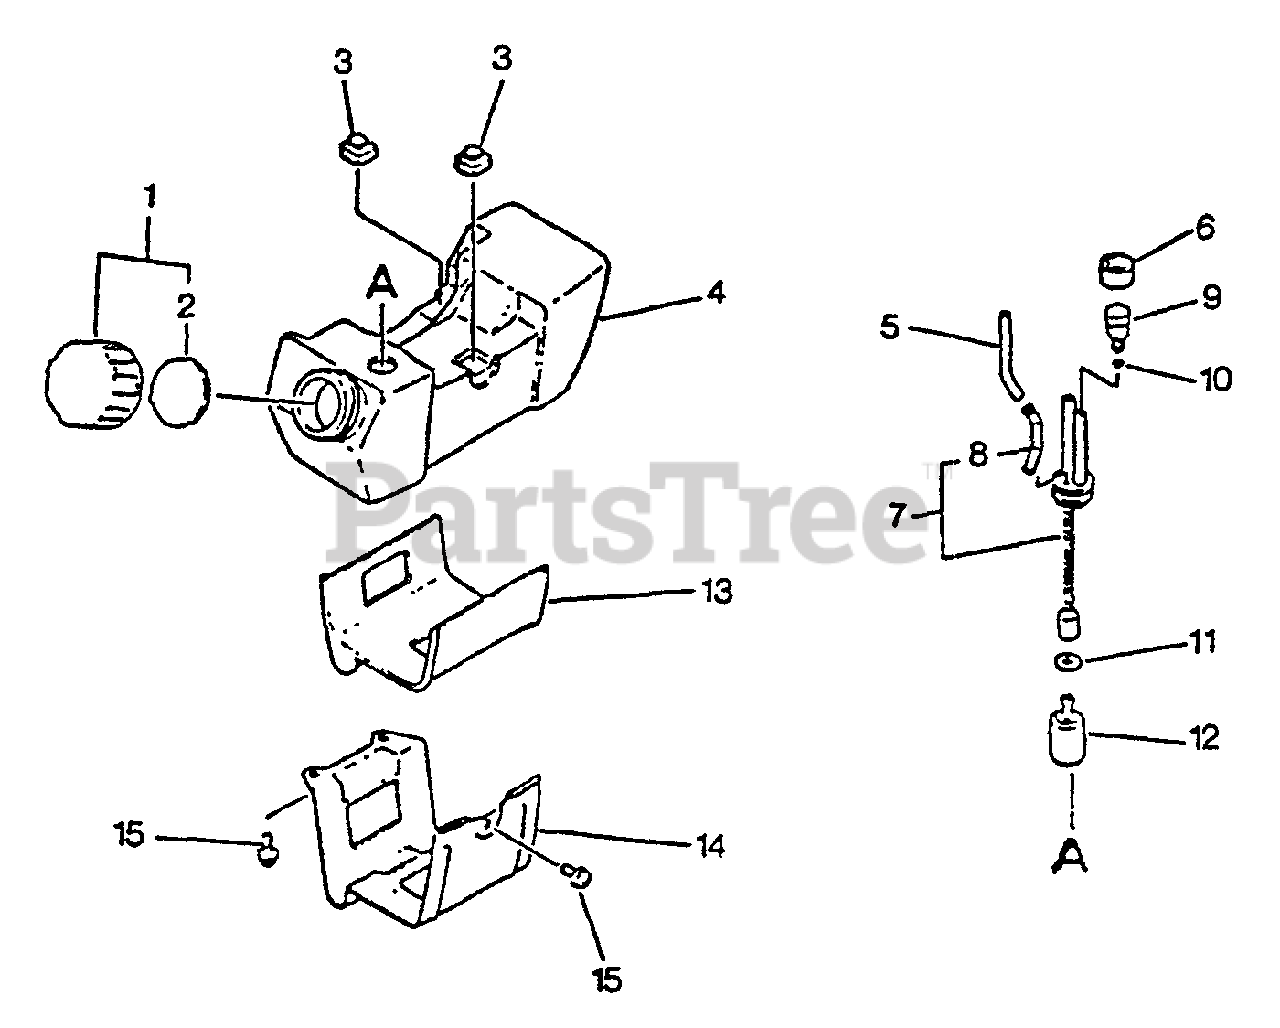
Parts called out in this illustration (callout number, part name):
1	CAP ASSY
2	GASKET, CAP
3	CUSHION
4	TANK, FUEL
5	PIPE - 3X6X45 -- CLEAR
6	COVER, VENT
7	FUEL SYSTEM KIT
8	CONNECTOR, PIPE
9	VENT, FUEL TANK
10	CLIP - 5.5
11	WASHER - 5
12	FILTER, FUEL
13	CUSHION
14	GUARD, FUEL TANK
15	SCREW - 5X10
